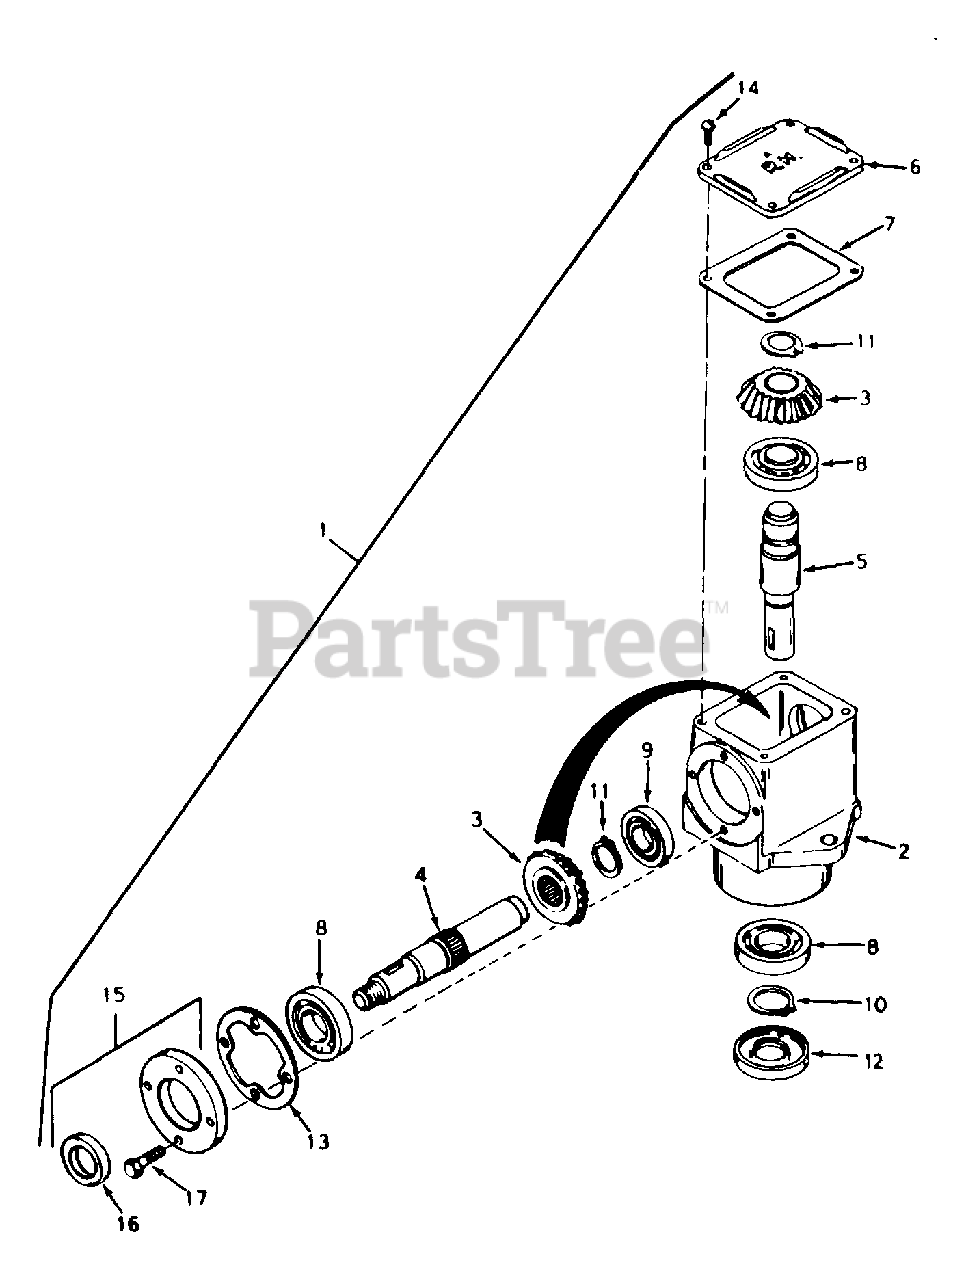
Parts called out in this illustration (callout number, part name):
1	Head Ass'y. R.H.
2	Housing, Right Angle Drive
3	Gear, Miter
4	Shaft, Input
5	Shaft, Output
6	Cover, Right Hand
7	Gasket, Cover
8	Bearing, Ball
9	Bearing, Ball
10	Ring, Snap
11	Ring, Snap
12	Seal, Oil
13	Gasket, Cap
14	Screw, Rd. Hd. Self-Tap. 10-24 x 1/2
15	Cap & Seal Ass'y., Retainer
16	Seal, Oil
17	Screw, Hex Hd. 1/4-20 x 7/8
2604-P91	Peerless Right Angle Drive Box
